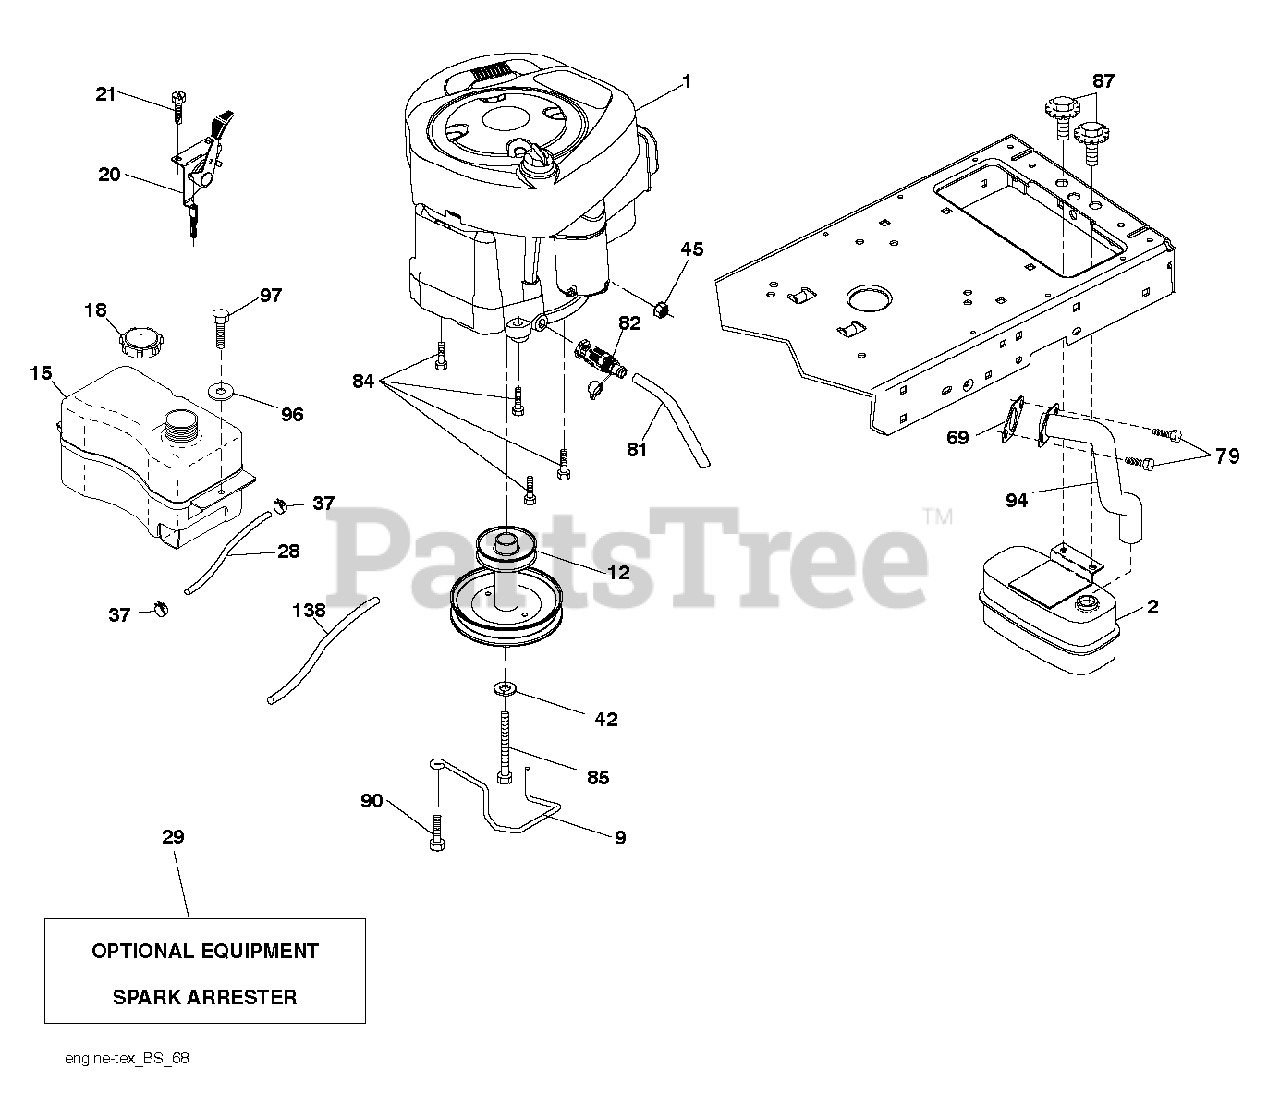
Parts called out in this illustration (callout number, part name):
2	MUFFLER.ASM.SNGL.XTNDED.DFLCTR
9	KEEPER.BELT.ENGINE.4.2
12	PULLY ENGINE
15	TANK.ASM.FRT.2.5 GAL.W/CAP.EPA
18	CAP.2.25'.VENTED.TETHER .EPA
20	CONTROL.TH/CK.COBRA.KO
21	SCREW.#10 X 0.750.BOS
28	LINE.FUEL.20"FRONT.EMI
29	KIT.SPARK ARRESTOR 794945 B&S
37	HOSE CLAMP
42	LOCKWASHER
45	NUT
69	REPL BY 532 27 22-93
79	SCREW.SOCKET HD.5/16-1
81	TUBE, DRAIN OIL ASM.
82	VALUE.OIL.DRAIN
84	SCREW.3/8-16
85	BOLT HEX 7/16-20X4-1/4"
87	BOLT, 5/16-18 X 1 3/4
90	SCREW 3/8-16X1
94	EXHAUST.TUBE.B&S.
97	SCREW HEXWSHR 1/4-20X3/4
138	RP PURGE LINE
